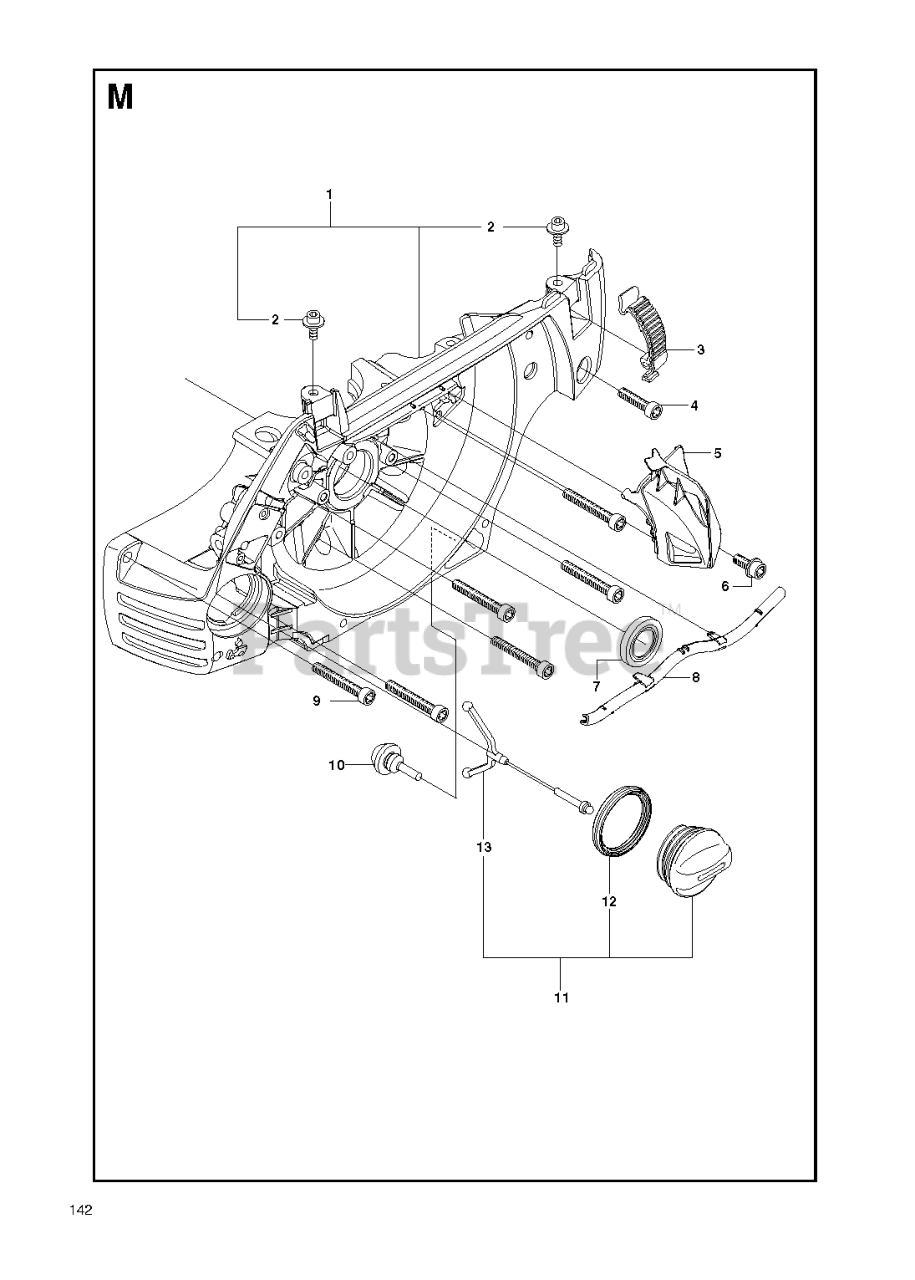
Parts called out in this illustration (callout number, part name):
1	CRANKCASE ASSY
2	RP SCREW
6	SCREW
7	SEAL RING
11	TANK CAP
12	SEALING
13	TANK LOCK
